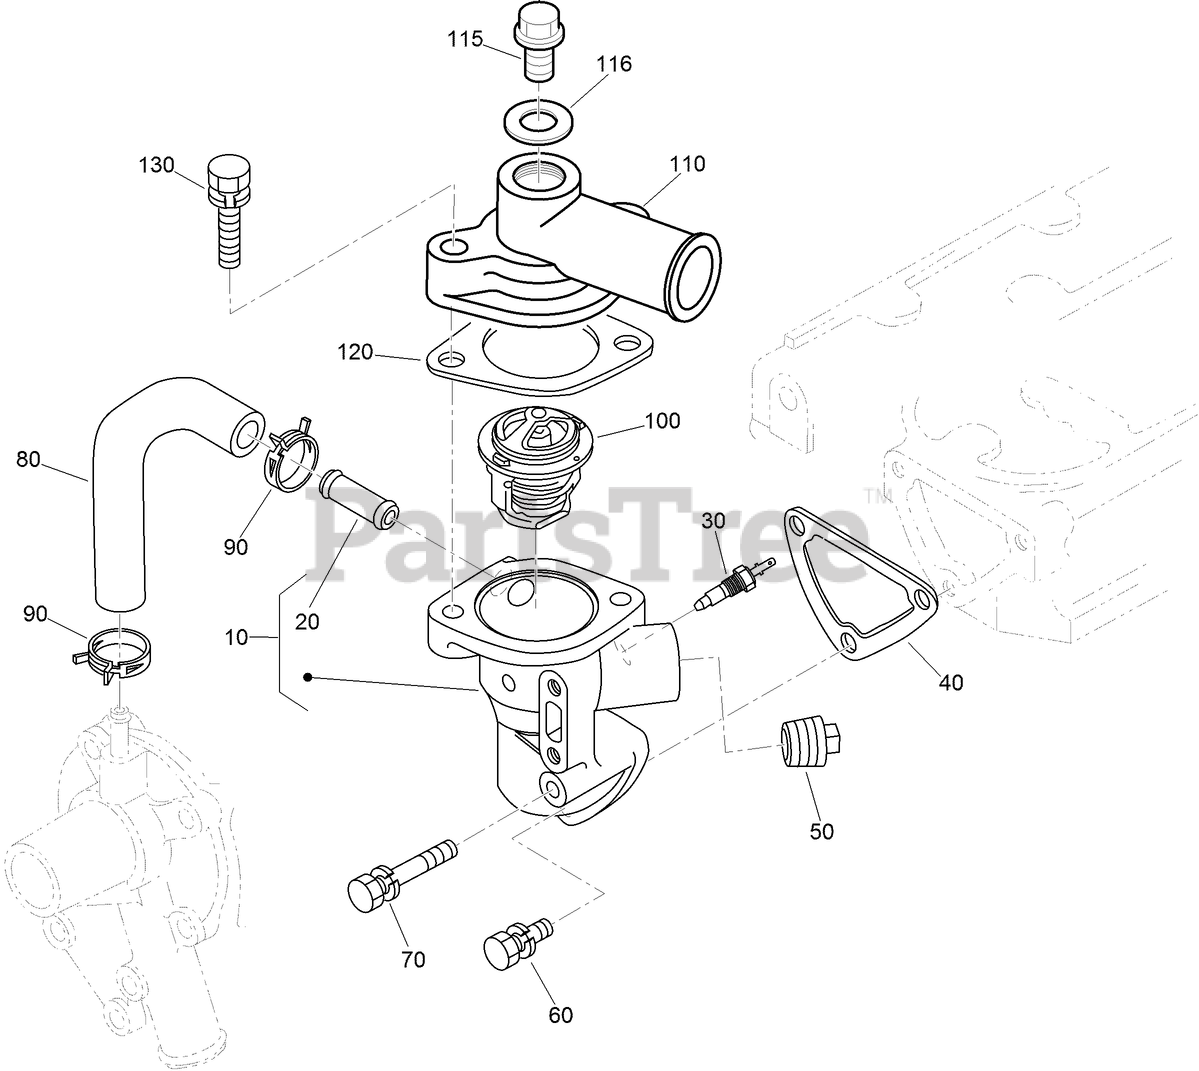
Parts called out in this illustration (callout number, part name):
10	WATER FLANGE ASM
20	PIPE-RETURN, WATER
30	THERMOSWITCH
40	GASKET-FLANGE, WATER
70	BOLT-SEMS
80	PIPE-RETURN, WATER
90	CLAMP-HOSE
100	THERMOSTAT ASM
110	COVER-THERMOSTAT
116	GASKET
120	GASKET-THERMOSTAT
